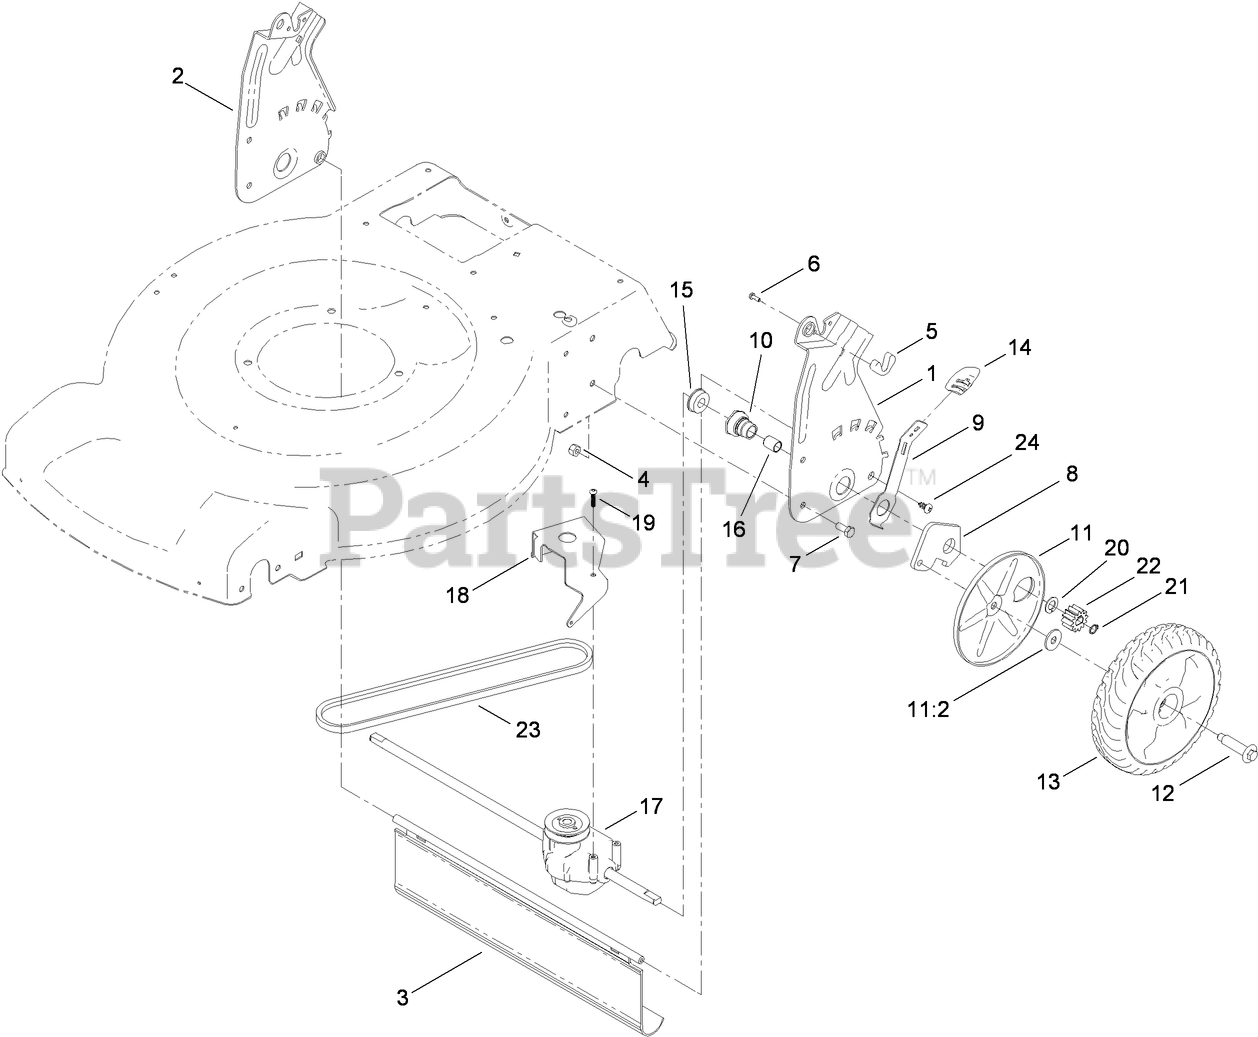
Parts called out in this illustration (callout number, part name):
4	NUT-LOCK, NI
5	ANCHOR-BAG
6	SCREW-PPH
7	SCREW-HH
8	ARM-PIVOT, REAR
9	ARM-SPRING
10	RETAINER-BUSHING, HOC
11:2	WASHER-STEPPED
12	BOLT-SHOULDER
14	KNOB-LEVER, HOC
15	BEARING-BALL
16	BUSHING-SLEEVE
18	BRACKET-TRANSMISSION
19	SCREW-PLASTITE
20	WASHER-THRUST
21	RING-RETAINING
22	GEAR-PINION
23	BELT-V
24	SCREW-PTH
